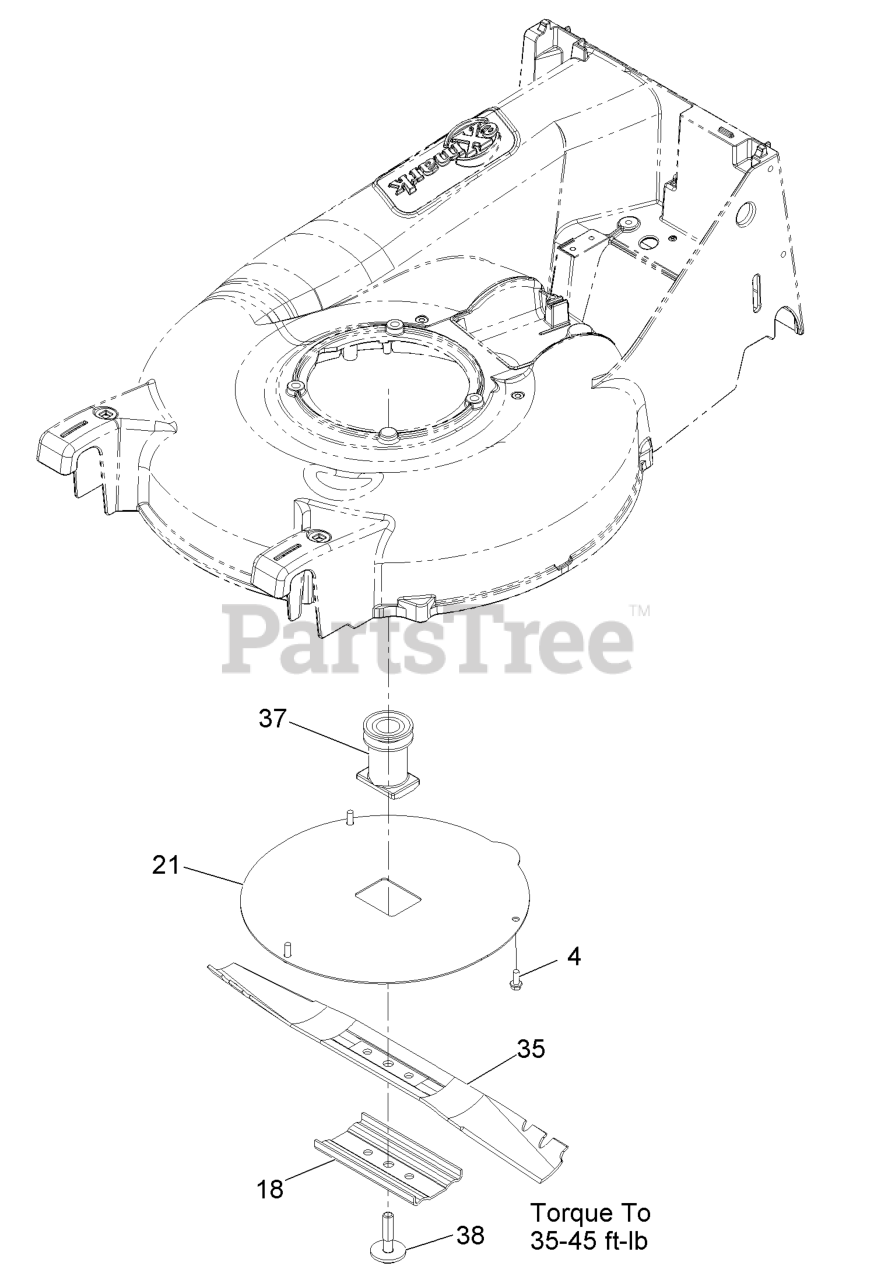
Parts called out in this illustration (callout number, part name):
4	SCREW-HWH
18	SUPPORT-BLADE
37	BLADE-ADAPTER
38	BOLT-BLADE, SEM
